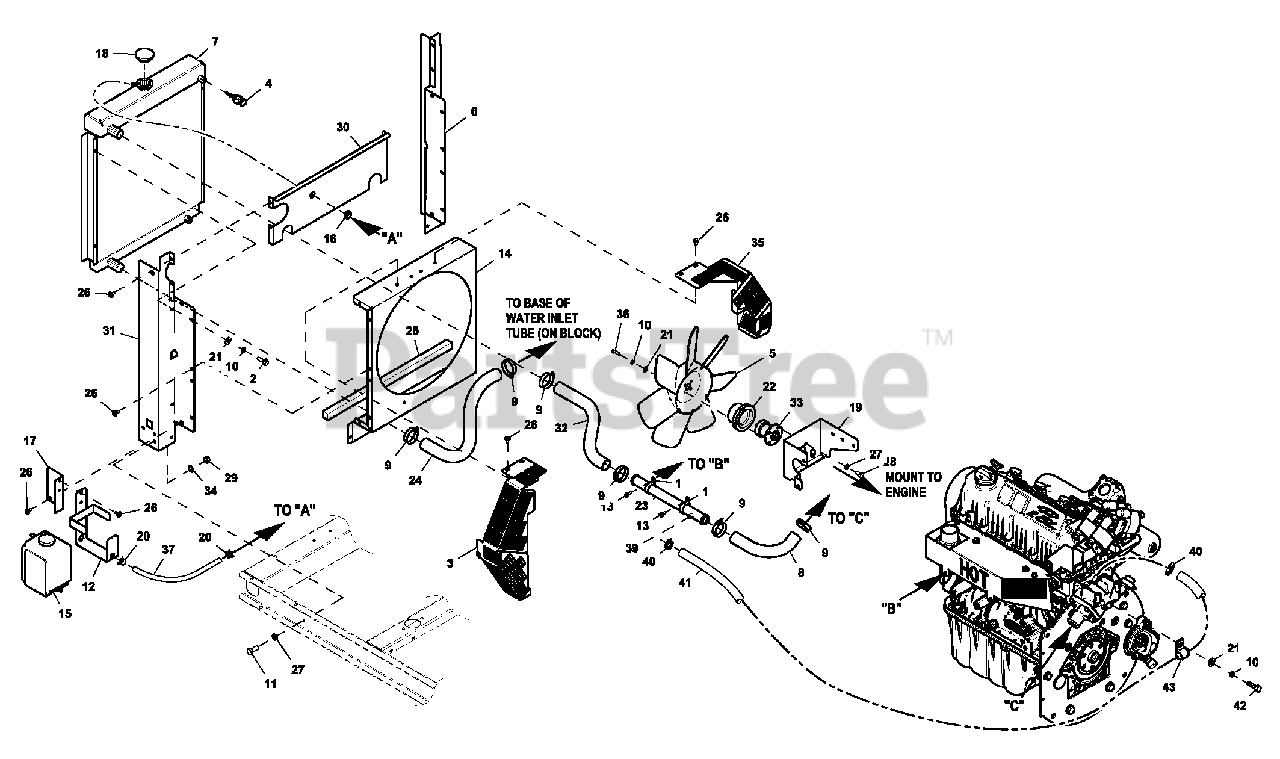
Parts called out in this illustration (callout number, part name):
1	CLAMP STL/VNL 1.31 X .281 Z
2	SCREW HHFC M6-1.0X20 G8.8
3	GUARD FAN LH C1
4	PROBE COOLANT LEVEL 3/8-18NPTF
5	FAN COOL 450MM DIA 7 BLADE
6	RADIATOR SUPPORT RH SIDE 1.6L
7	RADIATOR 1.6LG11
8	HOSE REAR COOLANT 1.5L
9	CLAMP HOSE #24 B1.06-2.00
10	WASHER LOCK M6-1/4
11	SCREW HHC M8-1.25X20 C8.8
12	BRACKET COOLANT TANK
13	SCREW HWHTF M6-1.0 X 16
14	VENTURI 1.6L
15	TANK COOLANT RECOVERY
16	GROMMET 5/8"X 1 1/8"X5/16"
17	BRACKET COOLANT OVERFLOW TANK
18	CAP RADIATOR 14PSI
19	BRKT FAN ALT ADAPTER 1.6L RAW
20	CLAMP HOSE BAND .50
21	WASHER FLAT 1/4-M6 ZINC
22	PULLEY - FAN 95 DIA
23	TUBE ENGINE COOLANT 1.5L
24	HOSE LOWER RADIATOR 1.6L
25	TAPE FOAM 1X1
26	SCREW HWHT M6-1 X 16 N WA Z/JS
27	WASHER LOCK M8-5/16
28	SCREW HHC M8-1.25X 16 C8.8
29	NUT HEX M8-1.25 G8 CLEAR ZINC
30	RADIATOR BLOCK-OFF
31	RADIATOR SUPPORT LH SIDE 1.6L
32	HOSE UPPER RADIATOR 1.6L
33	ASSY FAN BEARING SUPPORT
34	WASHER LOCK EXT 5/16 STL
35	GUARD FAN RH C1
36	SCREW HHC M6-1.0X20 C8.8
37	HOSE 9/32 ID (46.5" LG)
39	BARBED EL 90 5/16X 1/8NPT
40	CLAMP HOSE .38- 87
41	HOSE COOL 5/16" SAE 20R3 (33"LG)
42	SCREW HHC M6-1.0 X 16 C8.8
43	CLAMP STL/VNL .62X.406Z
